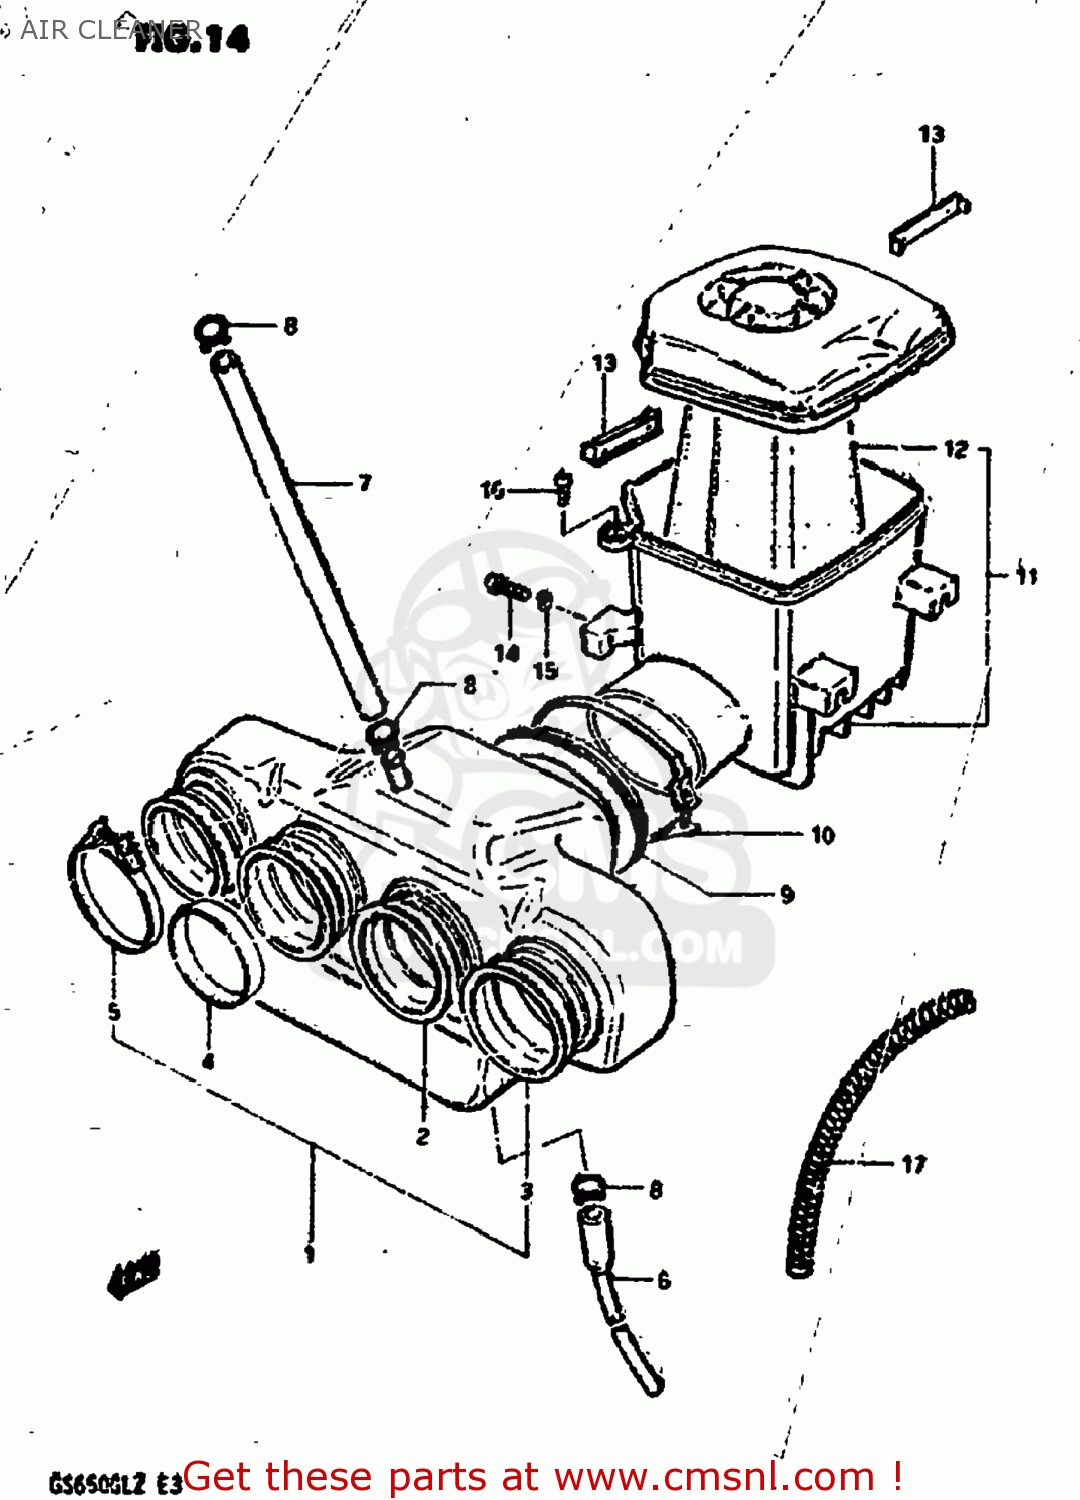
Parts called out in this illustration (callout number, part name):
1	CASE,AIR CLEANER,FRONT
2	TUBE,OUTLET,INNER
3	TUBE,OUTLET OUTER
4	RING,CARBURETOR AIR IN
5	CLAMP
6	DRAIN TUBE
7	HOSE
8	CLIP
9	JOINT,HOSE AIR CLEANER
10	CLAMP
11	CLEANER SET,AIR,REAR
12	FILTER ASSY
13	SLIDER
14	BOLT, UPPER
15	LOCK WASHER
16	SCREW
17	SPRING
